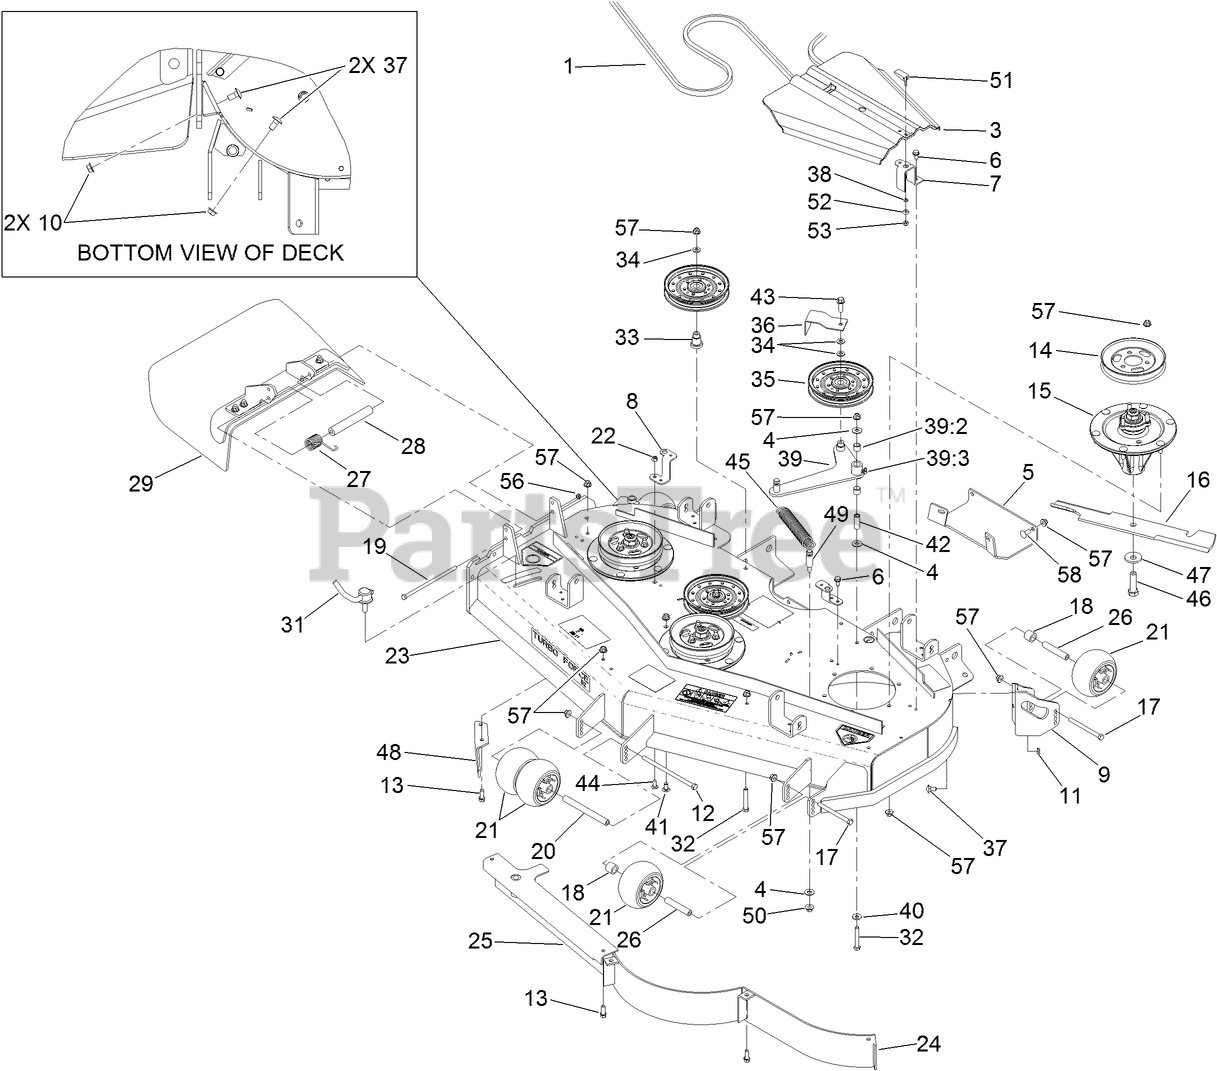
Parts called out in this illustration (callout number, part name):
1	BELT-V
3	COVER-BELT
4	WASHER-FLAT
5	Plate-Skid
6	SCREW-HWHTF
7	BRACKET-COVER
8	BRACKET-COVER, TALL
9	MOUNT-WHEEL, LH
10	NUT-HHF, WHIZ
11	NUT-LOCK, NI
12	SCREW-HH
13	SCREW-HWH
14	Pulley
15	SPINDLE ASM
16	BLADE-18IN, HI FLOW
17	SCREW-HH
18	TUBE-SPACER
19	SCREW-HH
20	SPACER-WHEEL
21	ROLLER-SCALP, ANTI
22	NUT-LOCK, NI
23	DECK DECAL ASM
26	TUBE-SPANNER
27	SPRING-TORSION
28	SPACER
29	RUBBER DEFLECTOR ASM
31	LEVER ASM
32	SCREW-HH
33	MOUNT-PULLEY
34	WASHER-FLAT
35	Idler-Flat
36	GUIDE-BELT
37	SCREW-CARR
38	WASHER
39	DECK IDLER ARM ASM
39:2	SLEEVE-BEARING
39:3	FITTING-GREASE, 90 DEG
40	WASHER-BELLEVILLE
41	SCREW-CARR
42	BUSHING
43	SCREW-HHF
44	SCREW-CARR
45	SPRING-EXTENSION
46	SCREW-BLADE
47	Washer-Blade Bolt, Heavy
48	BAFFLE-DISCHARGE
49	PIN-THREADED, SPRING ANCHOR
50	NUT-HF
51	HANDLE-LATCH, SWELL
52	BUSHING-LATCH, SWELL
53	NUT-LOCK, HH
56	NUT-LOCK, NI
57	NUT-HF, NI
58	SCREW-CARR
